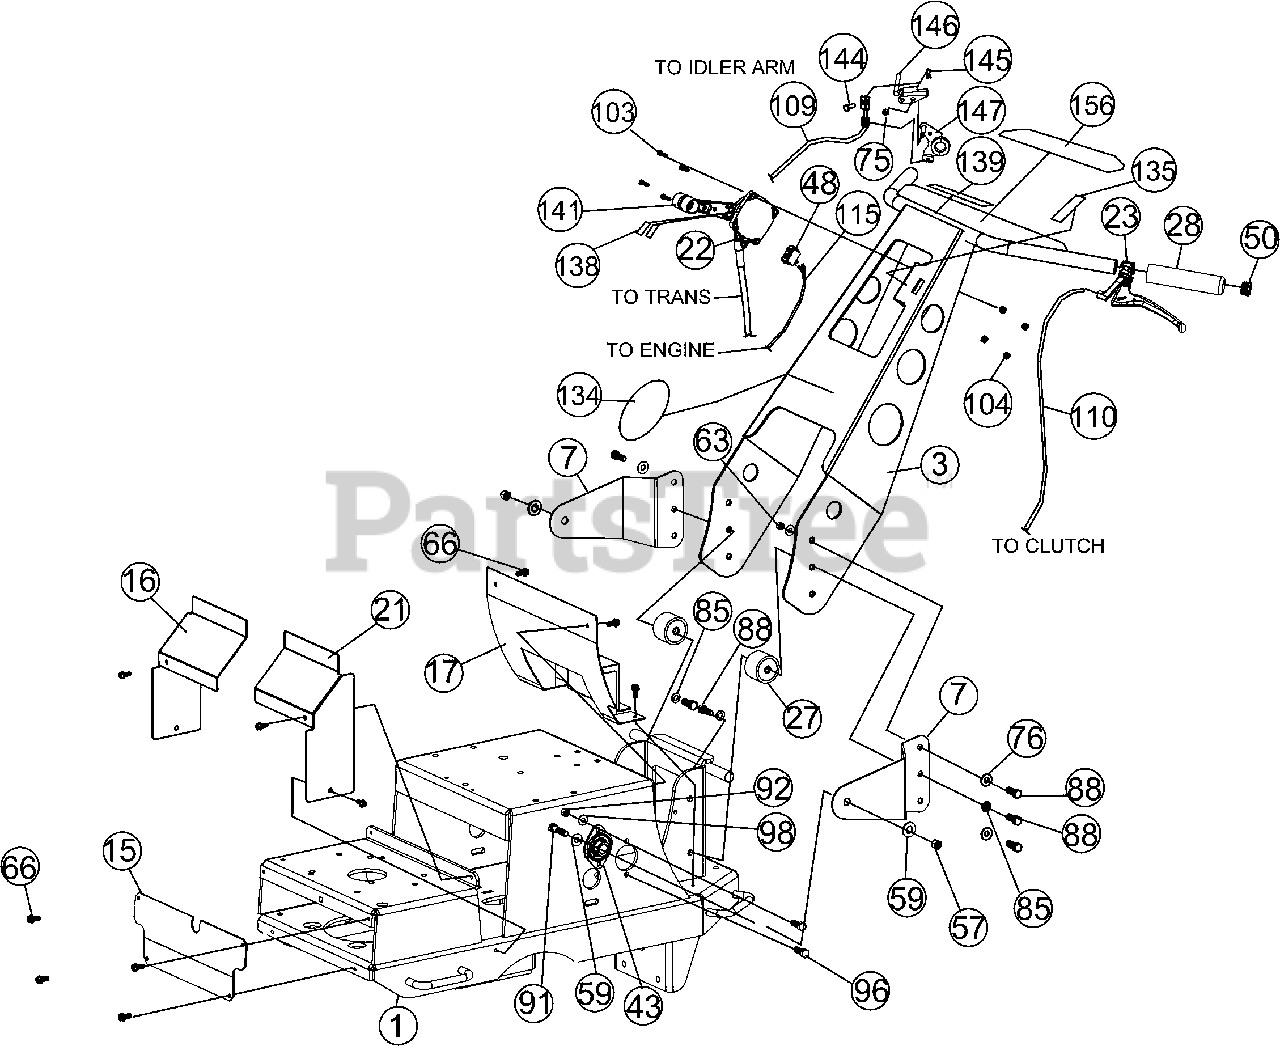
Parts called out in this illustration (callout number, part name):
3	HANDLE SC WA W/LABELS
7	HANDLE BRACKET MOUNT
15	GUARD FRONT
16	GUARD MID RIGHT
17	GUARD REAR WA
21	GUARD MID LEFT
22	SPEED CONTROL SC
23	CONTROL LEVER DRIVE
27	RUBBER HANDLE MOUNT
28	GRIP 1" X 5.5"
43	1/2" PRESSED STEEL HOUSING
48	SWITCH TOGGLE
50	PLUG TUBE 1"
57	NUT LOCK 1/2"-13 HEX
59	WASHER 1/2" SAE
63	NUT LOCK 3/8"-16
66	SCREW SELF TAP 1/4"-20 X 3/4" TYPE 23
75	NUT LOCK 5/16"-18 X 1 3/4" HCS ZP
76	WASHER 5/16" FLAT
85	LOCK WASHER 3/8" S/T MED
88	SCREWCAP 3/8"-16 X 1" HCS ZP
91	SCREWCAP 1/2"-13 X 1 3/4 HCS ZP
92	NUT LOCK 1/4"-20
96	SCREWCAP 1/4"-20 X 1" HCS ZP
98	WASHER 1/4" FLAT
103	SCREW MACH #10-24 X 3/4 WF ZP
104	NUT LOCK #10-24 HEX
109	CABLE CONTROL DRIVE QV
110	CABLE SPEED CONTROL LEFT SERVICE
115	WIRE HARNESS
134	LABEL PRODUCT LOGO CIRCLE LG
135	LABEL SHIFTER CONTROL
138	LABEL NEUTRAL SC18
139	LABEL HANDLE DRIVE SC18
141	HANDLE SPEED CONTROL SC18
144	PIN CLEVIS 0.25 X 0.50
145	PIN CLIP HITCH 0.51 X 3/4"
146	ARM CONTROL WA
147	CONTROL MOUNT HANDLE WA
156	LABEL CONSOLE SC
